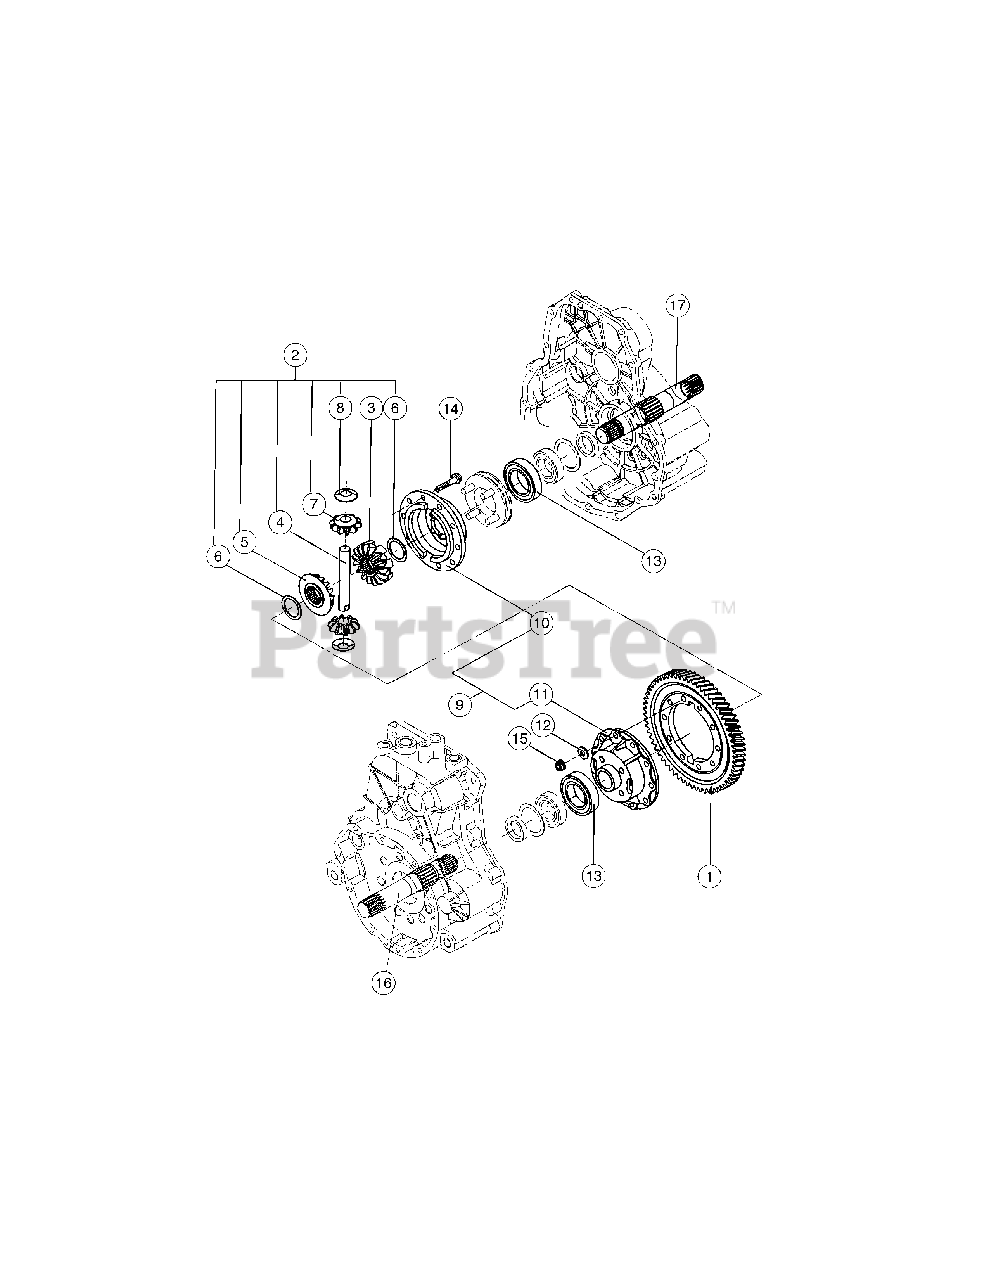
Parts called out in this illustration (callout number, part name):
1	Gear, 63H, Final
2	Differential, Gear Kit
3	Gear (RR, Differential)
4	Shaft, Differential Pinion
5	Differential Side Gear, RH
6	Washer, Differential Gear
7	Pinion, Differential
8	Washer, Differential Pinion
9	Differential, Case Kit
10	Case (R, Differential)
11	Case (L, Differential)
12	Washer, 8
13	Bearing, 6008
14	Bolt, 8 x 40
15	Nut, 8
